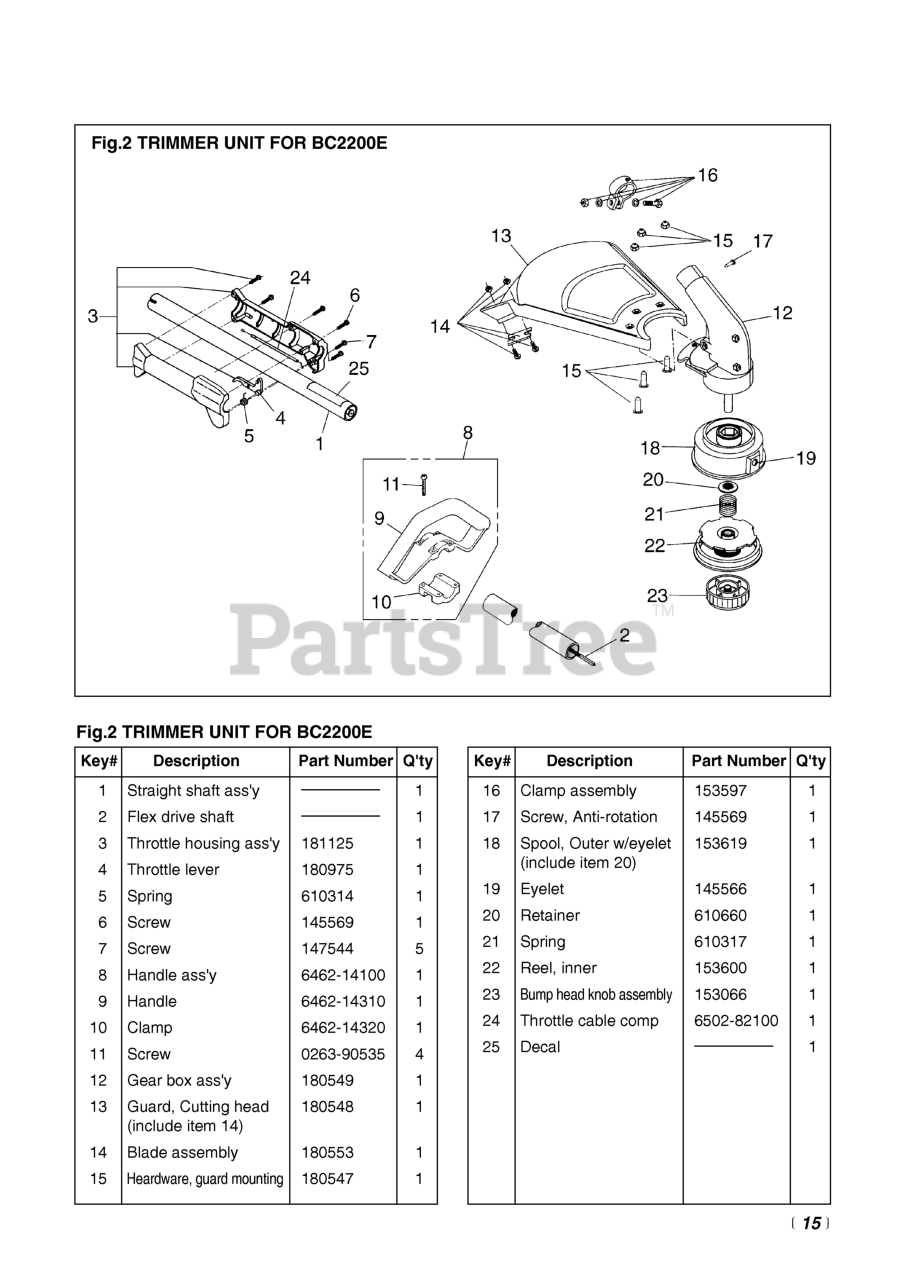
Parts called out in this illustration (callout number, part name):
1	STRAIGHT SHAFT ASSY
2	FLEX, DRIVE SHAFT
4	LEVER, THROTTLE
5	SPRING, THROTTLE TRIGGER
6	SET SCREW, ANTI-ROTATION
8	HANDLE ASSEMBLY
9	HANDLE
10	CLAMP
11	SCREW, M5 x 35
12	GEARBOX ASSEMBLY
13	ASSY, GUARD & BLADE
14	ASSY, BLADE
15	ASSY, GUARD MOUNTING SCREWS
16	CLAMP ASSY, LOWER
17	SET SCREW, ANTI-ROTATION
18	OUTER SPOOL ASSEMBLY
19	EYELET
20	WASHER, EYELET
24	CABLE COMP (RPLS 6460- )
25	DECAL
